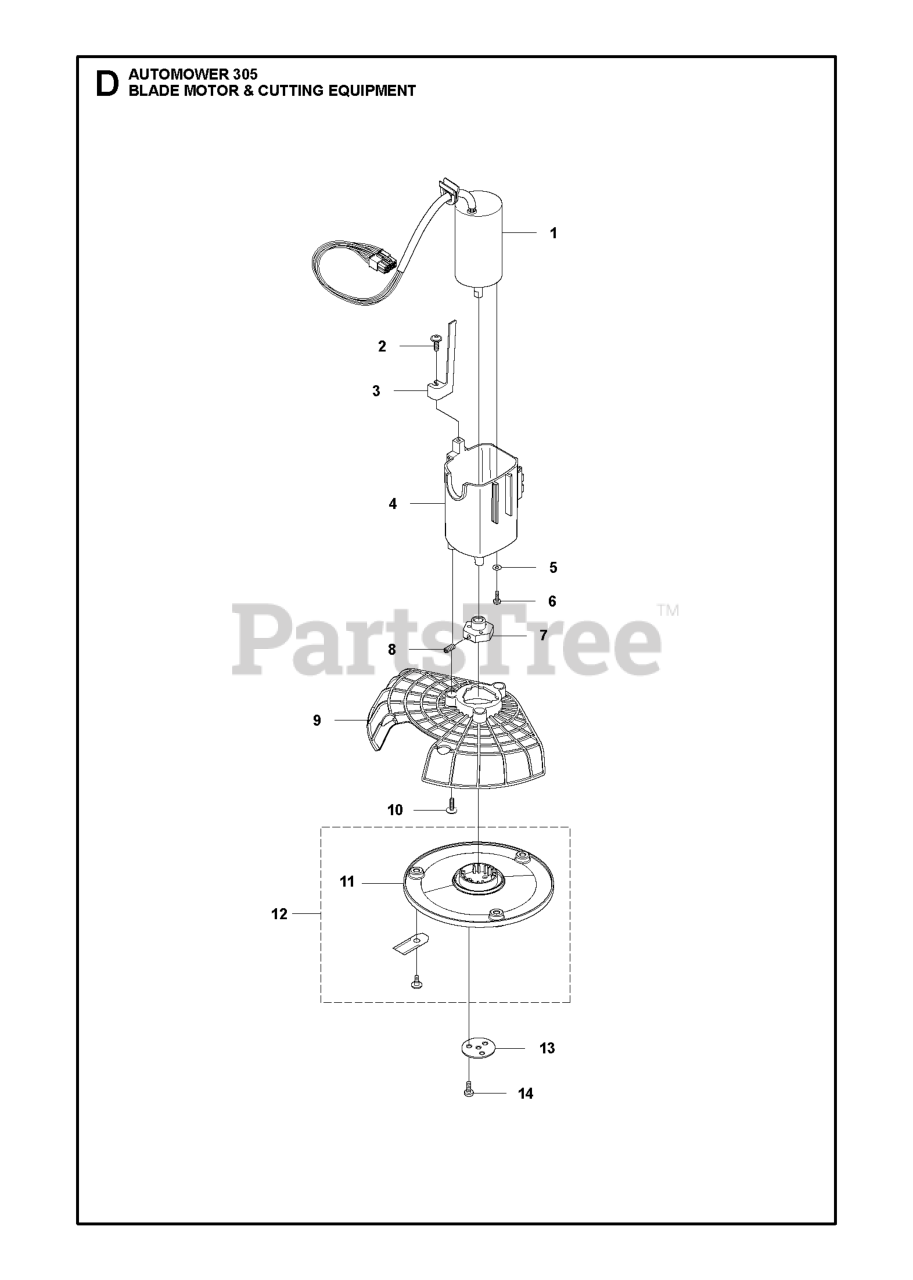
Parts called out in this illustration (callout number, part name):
2	SCREW 14MM
3	HEIGHT INDICATOR
7	HUB CUTTING MOTOR
8	SCREW IHSETM M5X10 8.8 ZP-BC
10	SCREW 14MM
11	CUTTING DISC
13	WASHER DRIVE WHEEL
14	SCREW ITXPANM M4X12 8.8 ZP-BC
